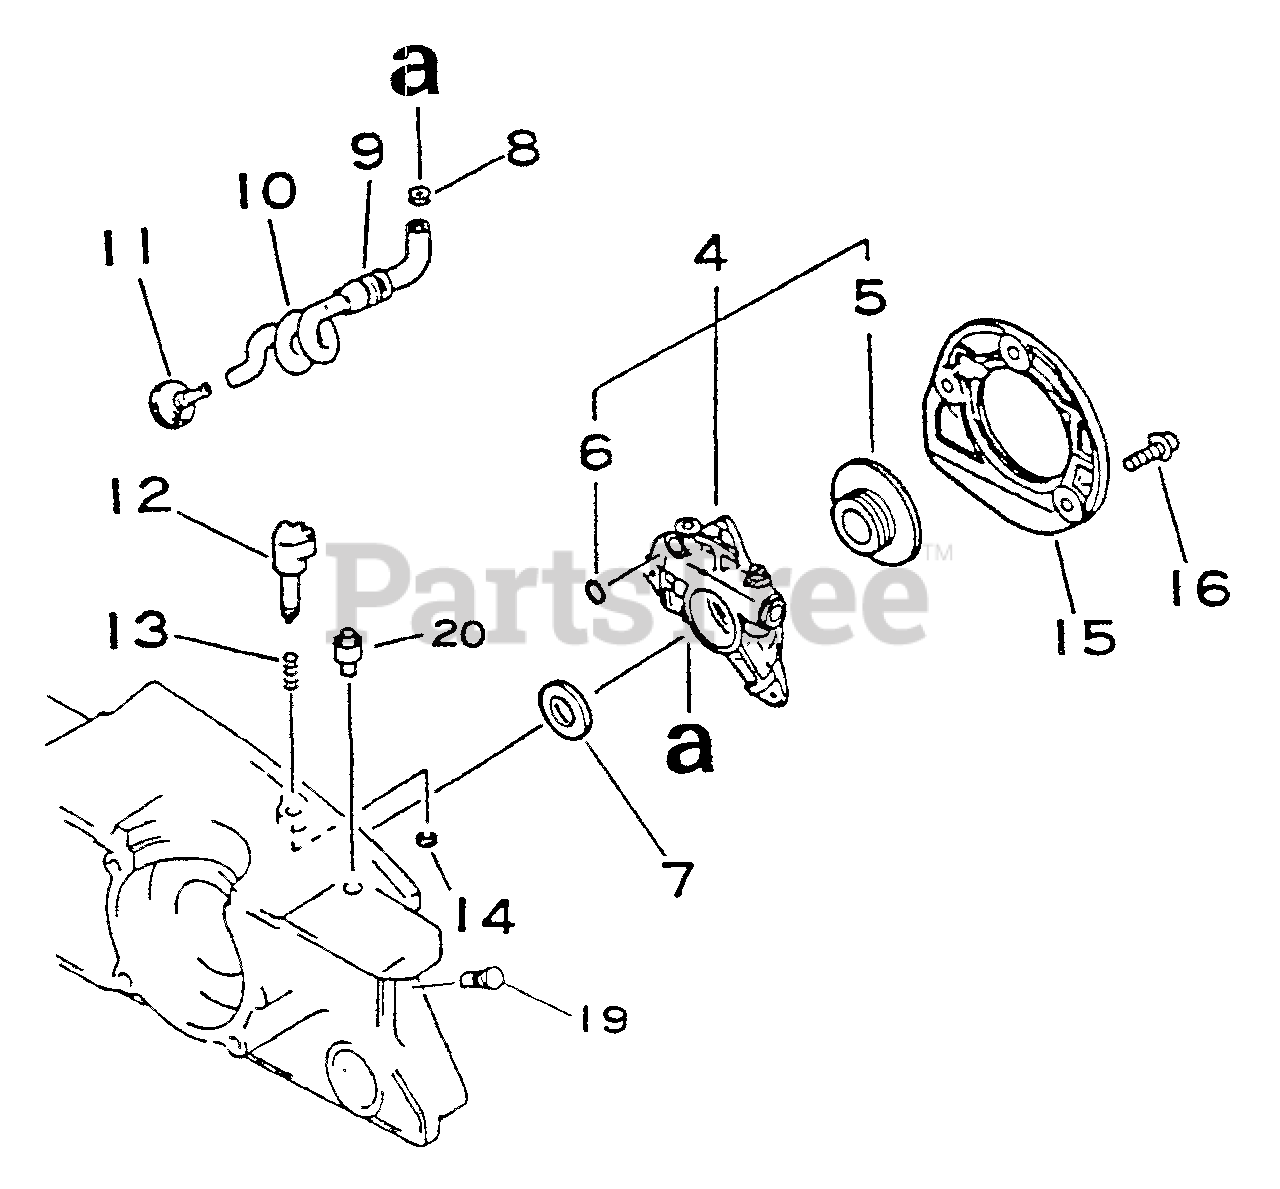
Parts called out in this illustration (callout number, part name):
4	AUTO-OILER ASSY
5	GEAR, WORM
6	O-RING 3
8	CLIP Ø6.5 MM
10	PIPE, OIL
11	FILTER, OIL
14	E-RING 3
15	COVER, OIL PUMP - ORANGE
16	SCREW - 4×14
19	PLUG
20	PLUG
